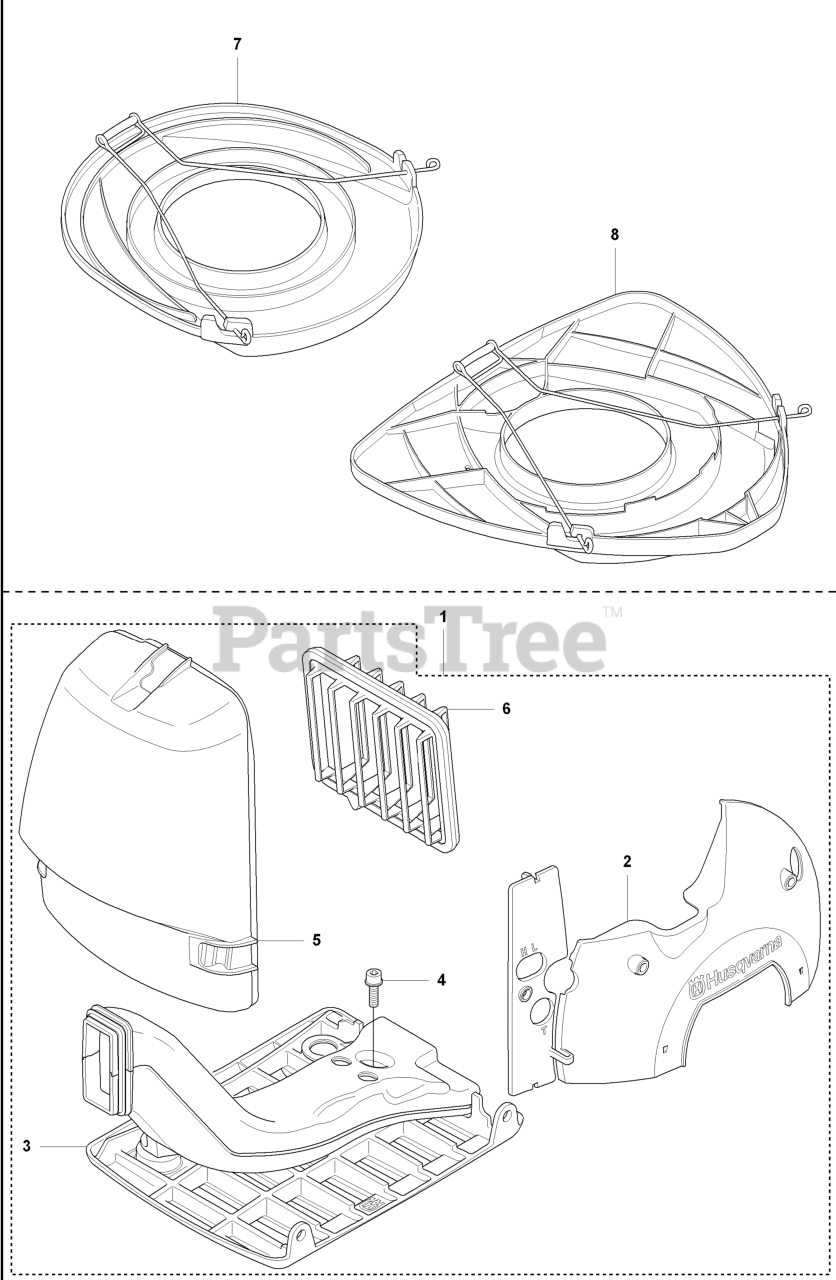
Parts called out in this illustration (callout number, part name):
2	WINTER COVER
6	FILTER
7	BLADE GUARD TRANSPORT
8	TRANSPORT GUARD
